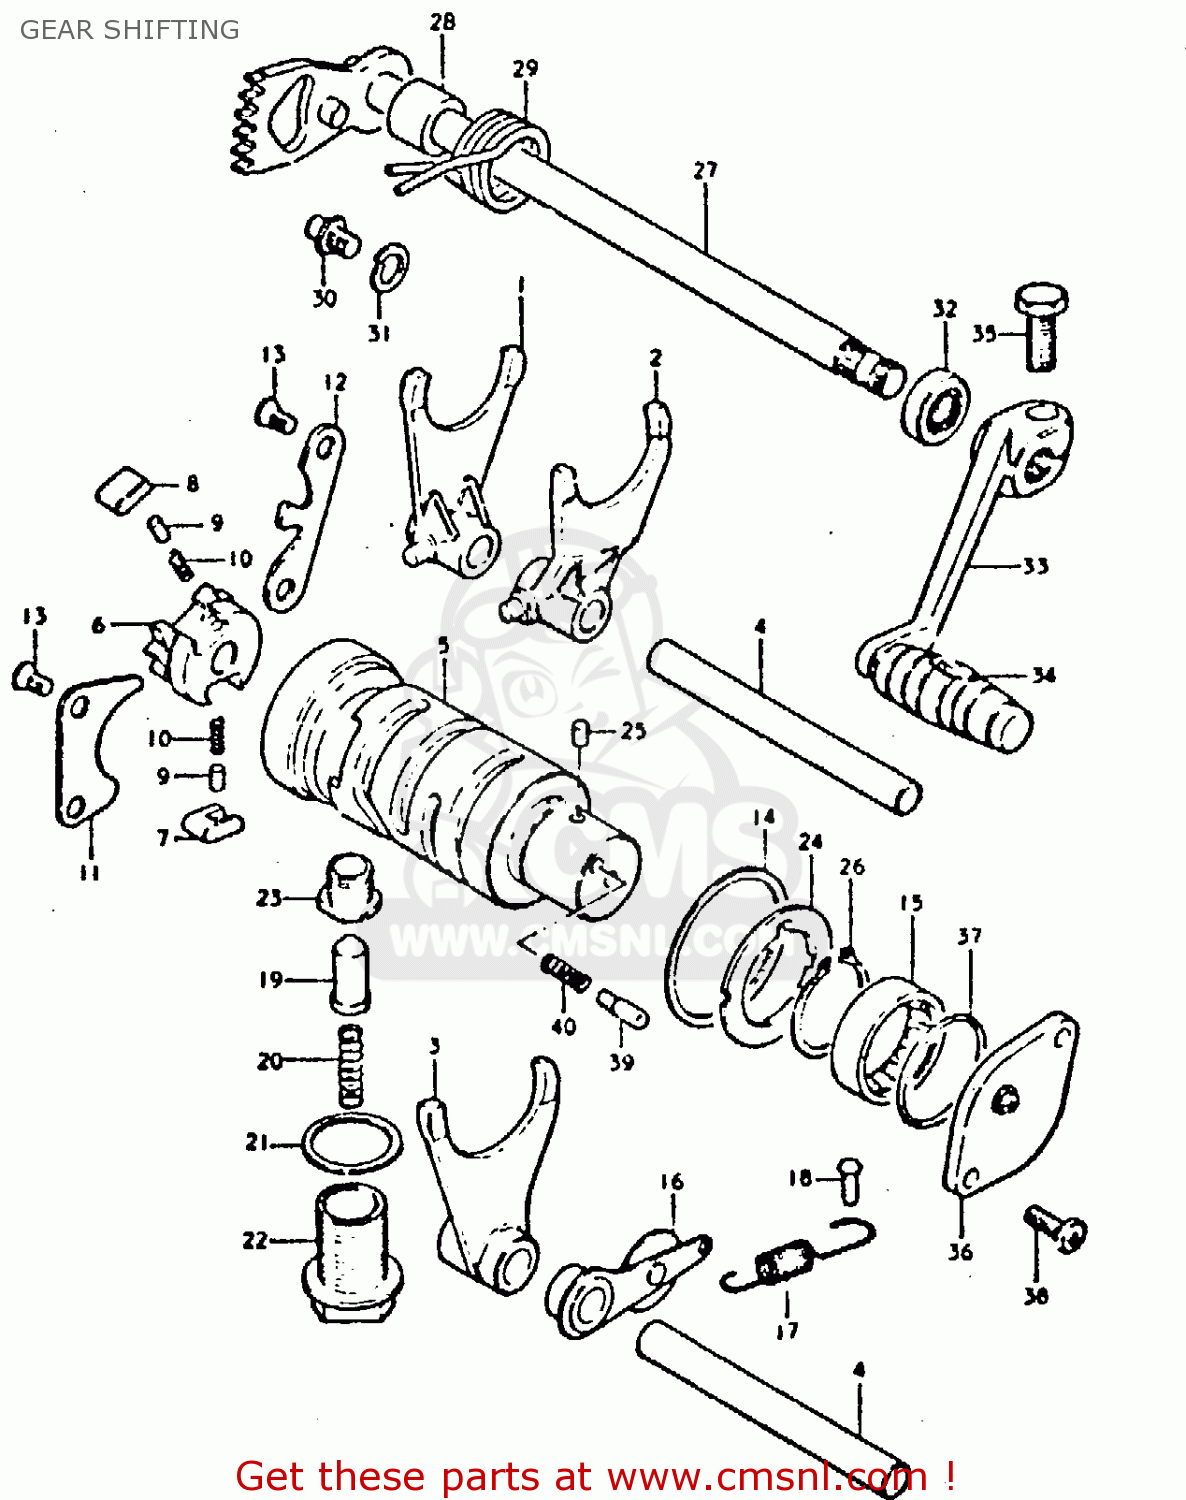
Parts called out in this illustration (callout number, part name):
1	FORK, GEAR SHIFTING NO. 1
2	FORK, GEAR SHIFTING NO. 2
3	FORK, GEAR SHIFT NO.3
4	SHAFT,GEAR SHIFT FORK
5	CAM, GEAR SHIFTING
6	RETAINER,GEAR SHIFT CAM
7	PAWL,GEAR SHIFT NO.1
8	PAWL,GEAR SHIFT NO.2
9	PIN(5X8)
10	SPRING
11	LIFTER,GEAR SHIFT PAWL
12	GUIDE,GEAR SHIFT CAM
13	SCREW
14	WASHER(40X45X1)
15	BEARING(25X32X12)
16	STOPPER, CAM NO. 1
17	SPRING
18	RIVET
19	STOPPER, CAM NO. 2
20	SPRING
21	GASKET(18X24.2X2) (NAS)
22	HOUSING, CAM STOPPER
23	GUIDE, CAM STOPPER
24	PLATE,GEAR SHIFT CAM STOPPER
25	PIN 4X6
26	CIRCLIP
27	SHAFT, GEAR SHIFTING
28	SPACER(12X20X15.3)
29	SPRING
30	STOPPER,GEAR SHIFT CAM
31	WASHER
32	OIL SEAL
33	LEVER ASSEMBLY,GEAR SHIFTING
34	RUBBER,GEAR SHIFT PEDAL
35	BOLT
36	BODY,GEAR SHIFT SWITCH
37	O-RING (D:2.4 ID:26.2)
38	SCREW
39	PIN(5X15.5)
40	SPRING
